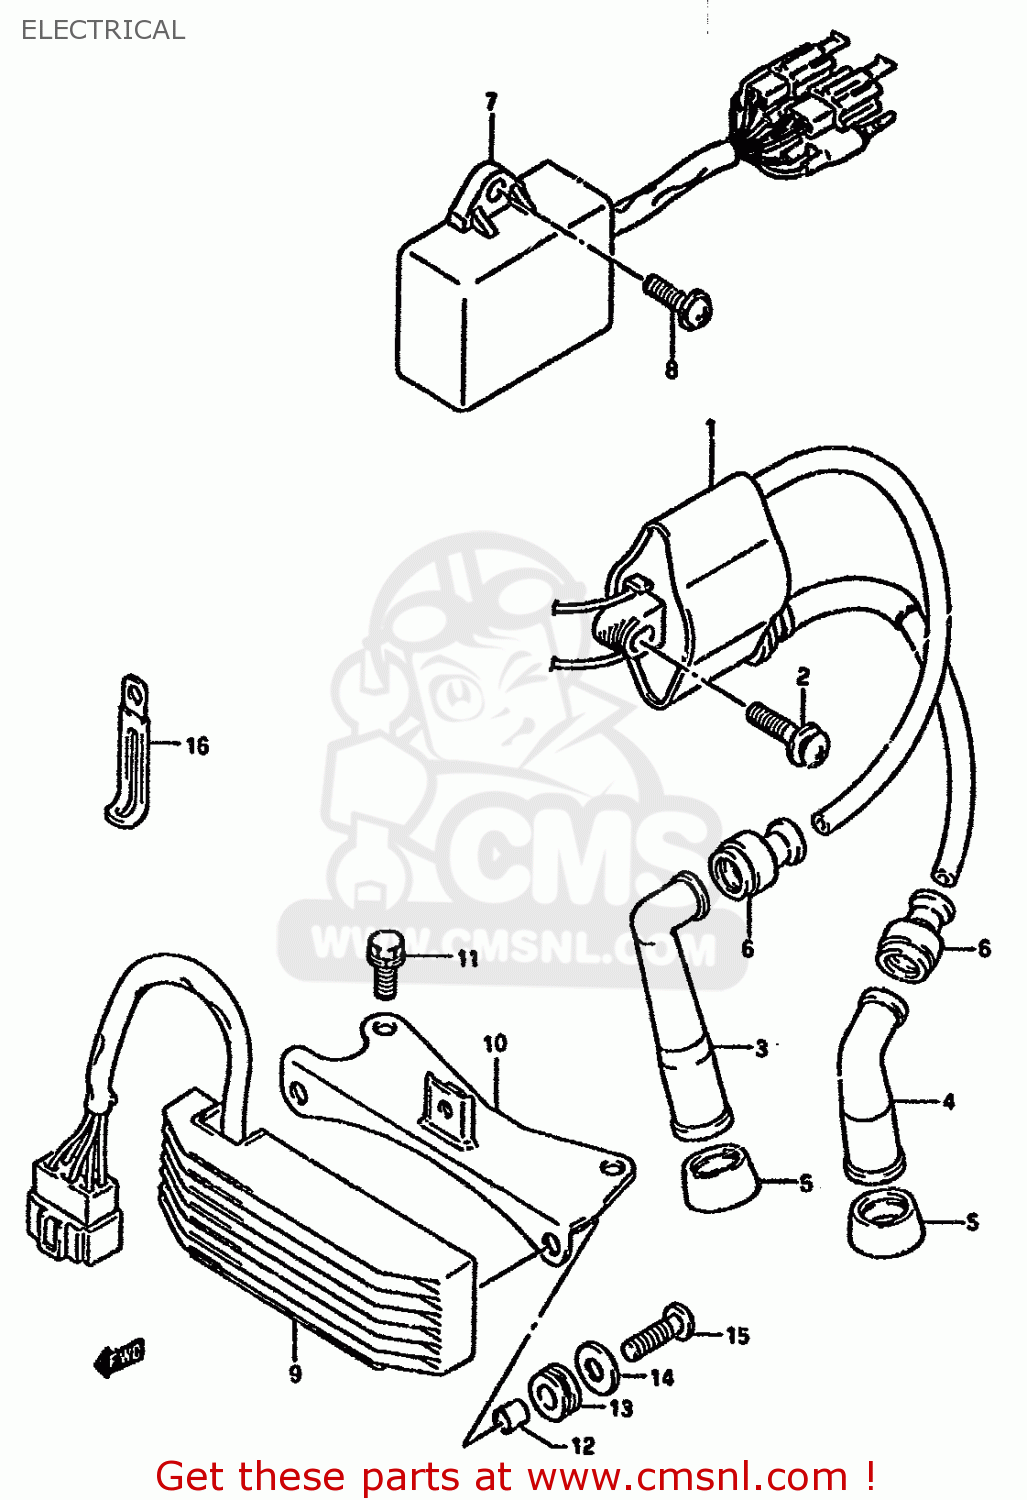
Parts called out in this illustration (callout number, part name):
1	COIL ASSY,IGNITION
2	SCREW
3	CAP ASSY,SPARK PLUG
4	CAP,SPARK PLUG
5	SEAL,SPARK PLUG CAP
6	SEAL,HIGH TENSION CORD
7	CDI UNIT
8	SCREW
9	RECTIFIER ASSEMBLY
10	BRACKET,RECTIFIER
11	BOLT
12	SPACER (6.1X8X9.5)
13	CUSHION
14	WASHER (6.5X18X1.6)
15	SCREW, CENTER
16	CLAMP
